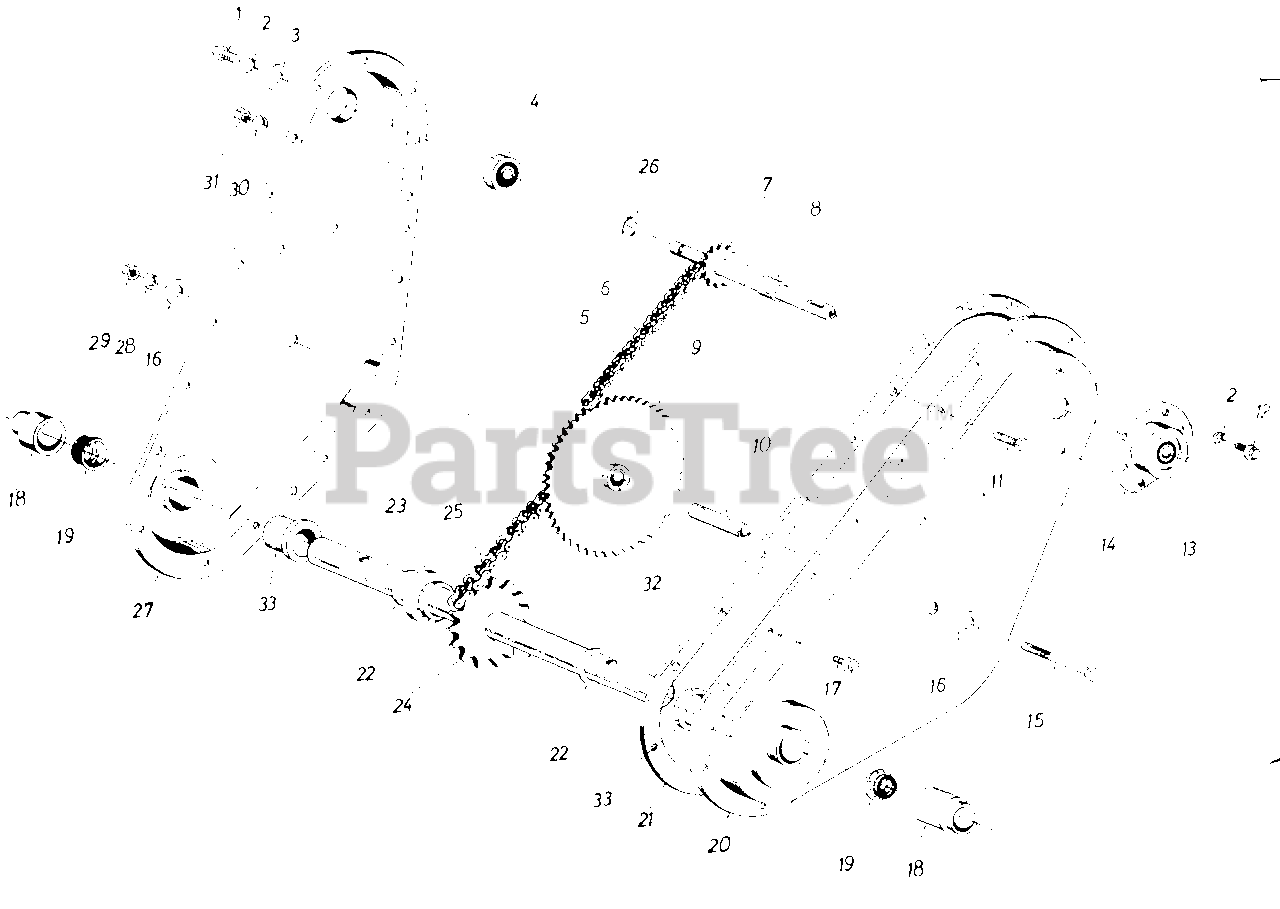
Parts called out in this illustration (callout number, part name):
1	Hex L-Scr. 1/4-28 x .625" Lg.
2	L-Wash. 1/4" I.D.
3	Fl-Wash. .25" I.D. x .93" O.D. x .125" Thk.
4	Bearing .62" I.D. x 1.38" O.D. x .437" Thk.
5	#35 Chain 3/8" Pitch x 52 Links-Endless
6	Master Link
7	1 nput Shaft Assembly
8	Spacer
9	Sprocket Assembly
10	Sprocket Hub Tubing 3/8" I.D. x 5/8" O.D. x 1.9" Lg.
11	Hex Scr. 5/16-18 x .625" Lg.
12	Hex Wash. Hd. Self-Tap Scr. 1/4-20 x .50" Lg.
13	Bearing .625" I.D. x 1.38" O.D. x .437" Thk.
14	Bearing Housing
15	Hex Scr. 3/8-24 x 2.75" Lg.
16	Fl-Wash. 3/8" I.D. x 1.25" O.D. x .100 Thk.
17	Hex Wash. Hd. Self-Tap Scr. 1/4-20 x .50" Lg.
18	Dust Cap
22	Thrust Wash. 1.00" I.D. x .030" Thk.
23	Step Spacer
24	Tine Shaft Assembly
25	#50 Chain 5/8" Pitch x 46 Links-Endless
26	Snap Ring
29	Hex Nut 3/8-24 Thd.
30	L-Wash. 5/16" Scr.
31	Hex Nut 5/16-18 Thd.
32	Bearing
33	Bearing
